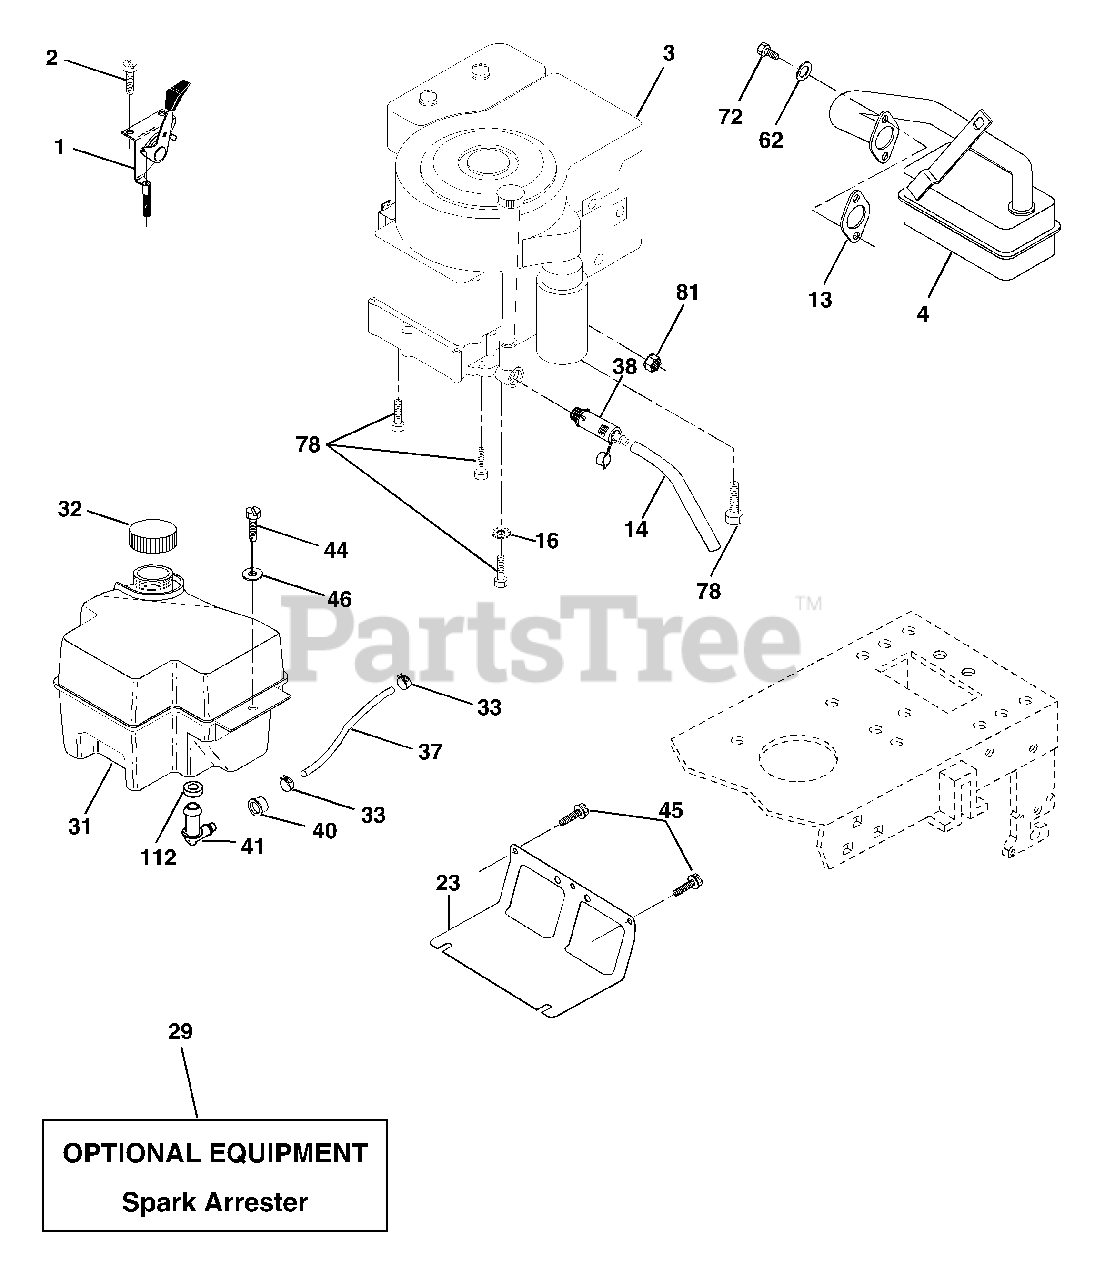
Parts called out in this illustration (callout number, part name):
1	Control Th/ch Flag
2	Screw Hex Thd Cut 1/4-20 x 1/2
4	Muffler
13	Gasket Eng
14	Tube Drain Oil Easy
16	Washer Lock Ext Tooth 3/8
23	Shield Brn/Dbr Guard
29	Kit Spark Arrestor (Flat Scrn)
31	Tank Fuel Front
32	Cap Asm Fuel W/sym Vented
33	Clamp Hose Black
37	Line Fuel 20"
38	Plug Drain Oil Easy
40	Bushing Snap Nyl Blk Fuel Line
41	Stem Tank Fuel
44	Screw Hexwsh Thdrol 1/4-20x3/4
45	Screw Hexwsh Thdr 3/8-16 x 3/4
46	Washer 9/32 X 7/8 X 16 Ga
62	Washer Lock Hvy Hlcl Spr 5/16
72	Screw Hex Hd Cap 5/16-18 x 3/4
78	Screw 3/8-16x1-1/4
81	Nut Keps Hex 1/4-20 UNC
112	Bushing
